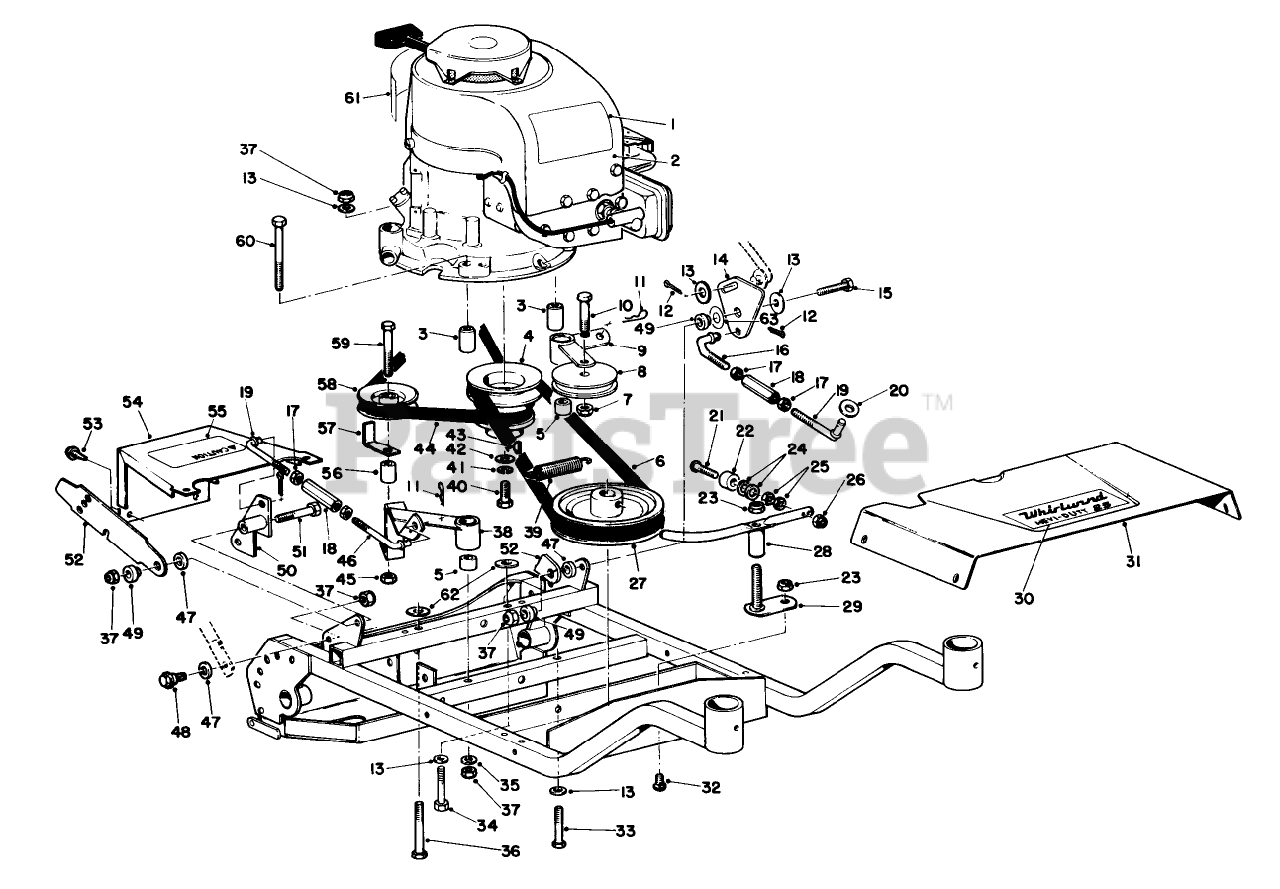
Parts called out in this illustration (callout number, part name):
1	Nut-Adjuster Lock
2	Adjuster Assembly
3	Steering Worm Assembly
6	Bolt-Flange Hex. Hd.
8	Side Cover Service Kit (Incl. Ref. #6, 9, 11 13)
10	Kit-Shim
11	Adjuster
12	Gear-Pitman Shaft
13	Gasket
14	Housing-Steering Gear
15	Assembly-Thrust Bearing
